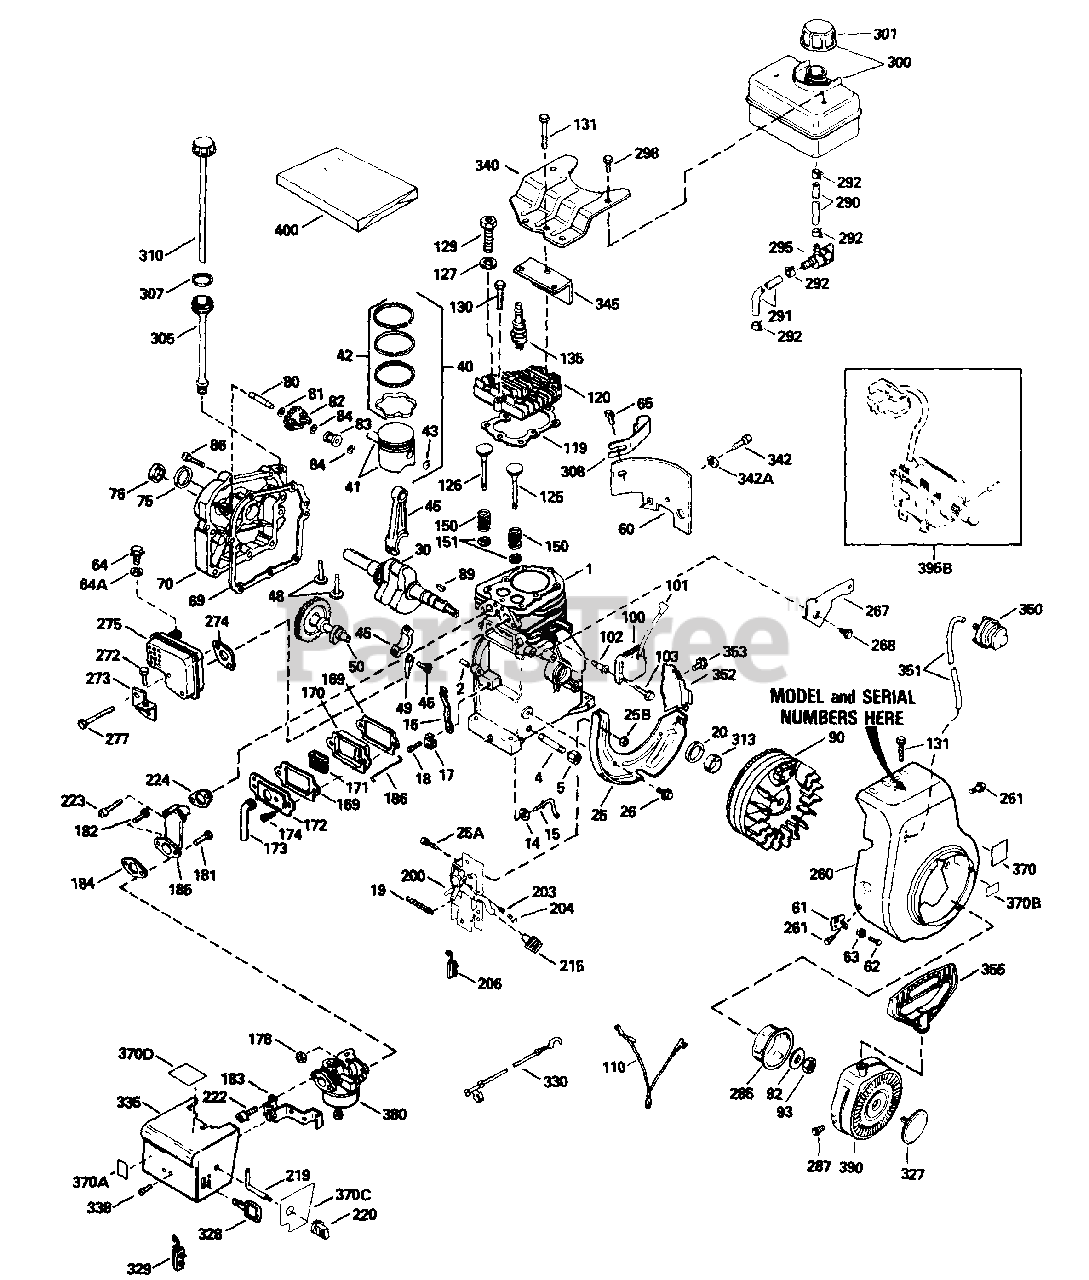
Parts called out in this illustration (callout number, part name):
1	Cylinder Ass'y.
2	Pin, Dowel
4	Nipple, Pipe
5	Cap, Oil Drain
14	Washer, Flat
15	Rod, Governor
16	Lever, Governor
17	Clamp, Governor Lever
18	Screw, Hex Washer Hd., 8-32 x 5/16
19	Spring, Extension
20	Seal, Oil
25	Baffle, Lower Housing
25A	Screw, Fil. Hd. Sems, 8-32 x 1/2
25B	Nut, Lock, 8-32
26	Screw, Hex Washer Hd. Durlok, 1/4-20 x 5/8
30	Crankshaft Ass'y.
40	Piston, Pin & Ring Ass'y. (Std.)
40	Piston, Pin & Ring Ass'y. (.010 Oversized)
40	Piston, Pin & Ring Ass'y. (.020 Oversize)
41	Piston & Pin Ass'y. (Std.)
41	Piston & Pin Ass'y. (.010 Oversize)
41	Piston & Pin Ass'y. (.020 Oversize)
42	Ring Set, Piston (Std.)
42	Ring Set, Piston (.010 Oversize)
42	Ring Set, Piston (.020 Oversize)
43	Ring, Piston Pin Retaining
45	Rod Ass'y., Connecting
46	Bolt, Connecting Rod
48	Lifter, Valve
49	Dipper, Oil
50	Camshaft (Compression Release)
60	Extension, Blower Housing
61	Bracket, Grommet Mounting
62	Screw, Pan Hd. Taptite, 8-32 x 3/8
63	Grommet, Plastic
64	Screw, Torx T-30 Hex Washer Hd. Sems, 1/4-20 x 1/2
64A	Washer, Flat
65	Screw, Hex Hd. Sems, 10-24 x 1/2
69	Gasket, Cylinder Cover
70	Cover, Cylinder
75	Seal, Oil
76	Seal, Camshaft
80	Shaft, Mechanical Governor
81	Washer, Flat
82	Gear, Governor
83	Spool, Governor
84	Ring, Retaining
86	Screw, Hex Hd. Sems, 1/4-20 x 1-1/4
89	Key, Flywheel
90	Flywheel (w/Ring Gear)
92	Washer, Belleville
93	Nut, Flywheel
100	Solid State Ass'y.
101	Cover, Spark Plug
102	Stud, Solid State Mounting
103	Screw, Torx T-15 Hex Washer Hd. Sems, 10-24 x 1
110	Ground Wire
119	USE TC-36443 GASKET
120	CYLINDER HEAD
125	EXHAUST VALVEA
125	EXHAUST VALVE
126	VALVE-INTA
126	Valve, Intake (1/32" Oversize)
135	Spark Plug, J8C
150	Spring, Valve
151	CAP-VALVE SPRING
169	VALVE COVER GASKET
170	BODY-VALVE
171	Air Cleaner
172	BREATHER COVER
178	Nut and Lockwasher, 1/4-28
181	Screw, Hex Hd., 1/4-28 x 7/8
183	Choke Bracket
184	GASKET
185	PIPE-INTAK
186	GOVERNOR LINK
200	Control Assembly
203	Compression Spring
204	Torx Screw
206	Terminal Ass'y.
215	Control Knob
219	Choke Rod
220	Control Knob
222	USE TC-651081 SCREW
223	Screw, Fil. Hd. Sems, 1/4 - 20 x 1 - 19/32
224	GASKET-INT
260	BLOWER HOUSING
261	Screw, Hex Hd. Sems, 1/4-28 x 7/16
267	Bracket, Hold Down
274	EXHAUST GASKET
275	Muffler
277	Screw
285	CUP-STARTE
287	Screw, Hex Washer Hd., 8-32 x 1/2
290	FUEL LINE
291	Fuel Line
292	Fuel Line Clamp
295	Fuel Fitting
300	Fuel Tank
301	Fuel Cap
305	Oil Fill Tube
308	Oil Fill Clip
327	PLUG-START
328	Ignition Key
330	WIRE-GROUN
335	USE TC-35072B COVER-CARB
338	Screw, Pan Hd. Sems, 8-32 x 5/16
340	PLATE-FUEL
342	Screw, 1/4-20 X 1/2"
342A	Washer, Flat
345	BAFFLE-HEA
350	Primer Bulb and Body Assembly
351	Primer Line
352	ETENSION-B
353	Screw, Hex Wash. Hd., 8-32 x 1/2
355	Starter Handle
370A	DECAL-INSTRUCTION
380	Carburetor
390	Recoil Starter
400	USE TC-33683C GASKET SET
